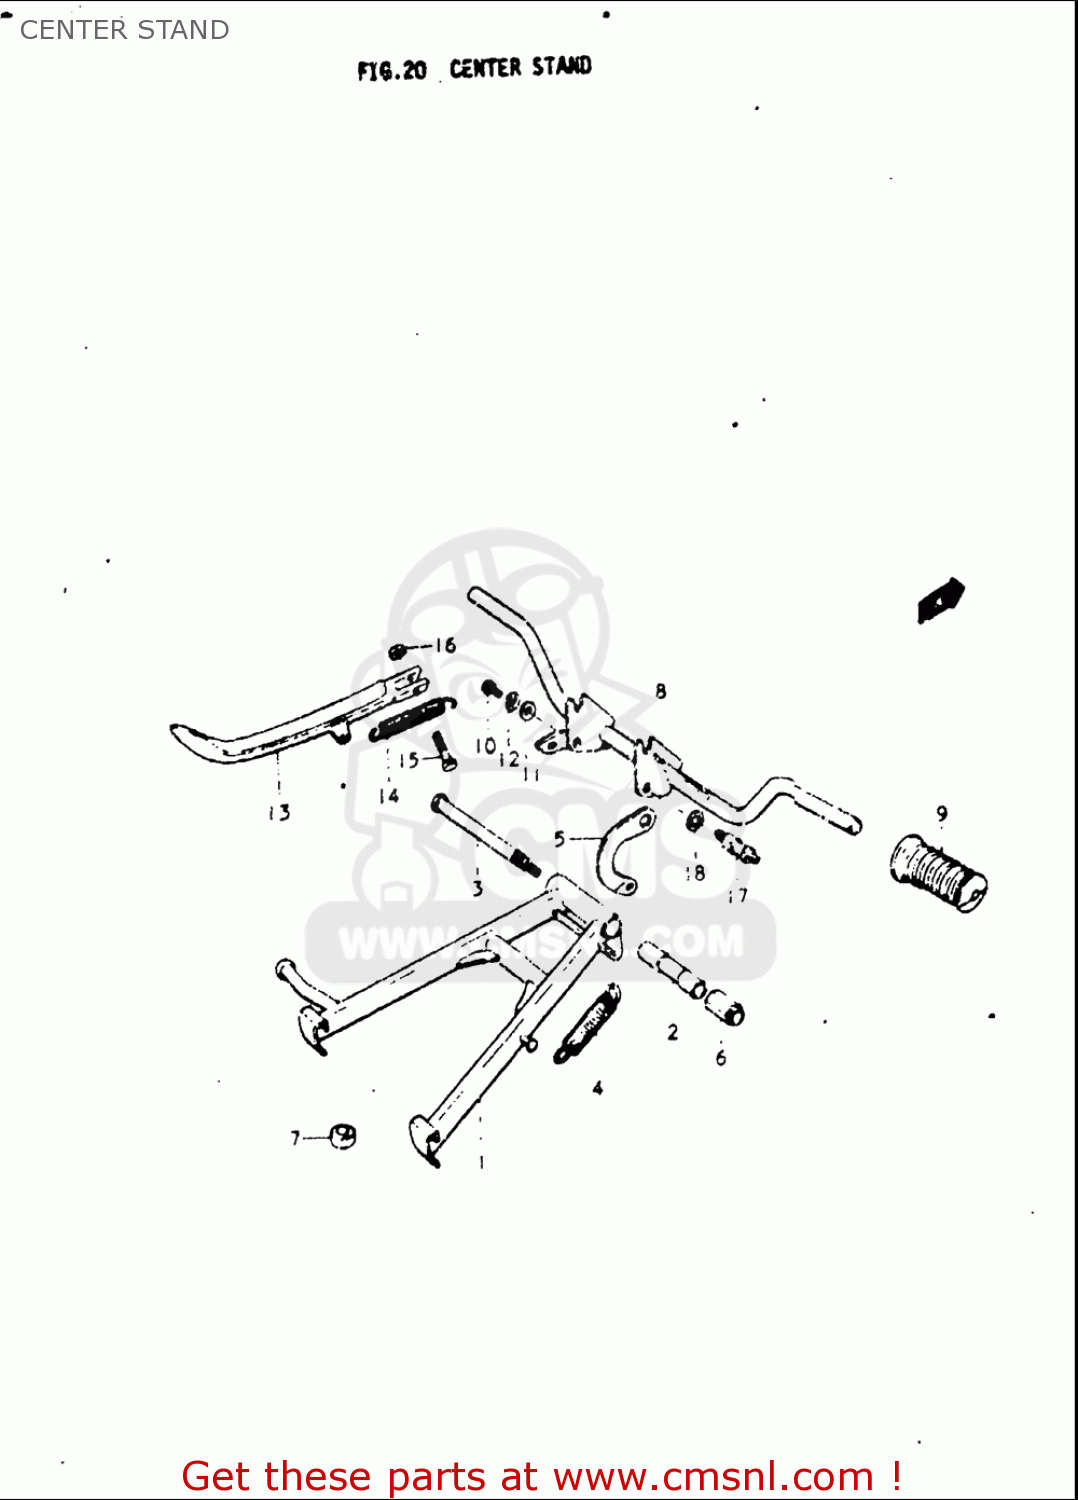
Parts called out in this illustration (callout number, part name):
1	STAND,CTR
2	SPACER
4	SPRING
5	HOOK,CENTER STAND SPRING
7	CUSHION
8	BAR,FR FOOTREST
9	RUBBER,FR FOOTREST
10	BOLT
11	WASHER
12	WASHER,LOCK
13	STAND,SIDE
14	SPRING
15	BOLT(10X27)
16	NUT
17	STOPPER,BRAKE PEDAL
18	WASHER
